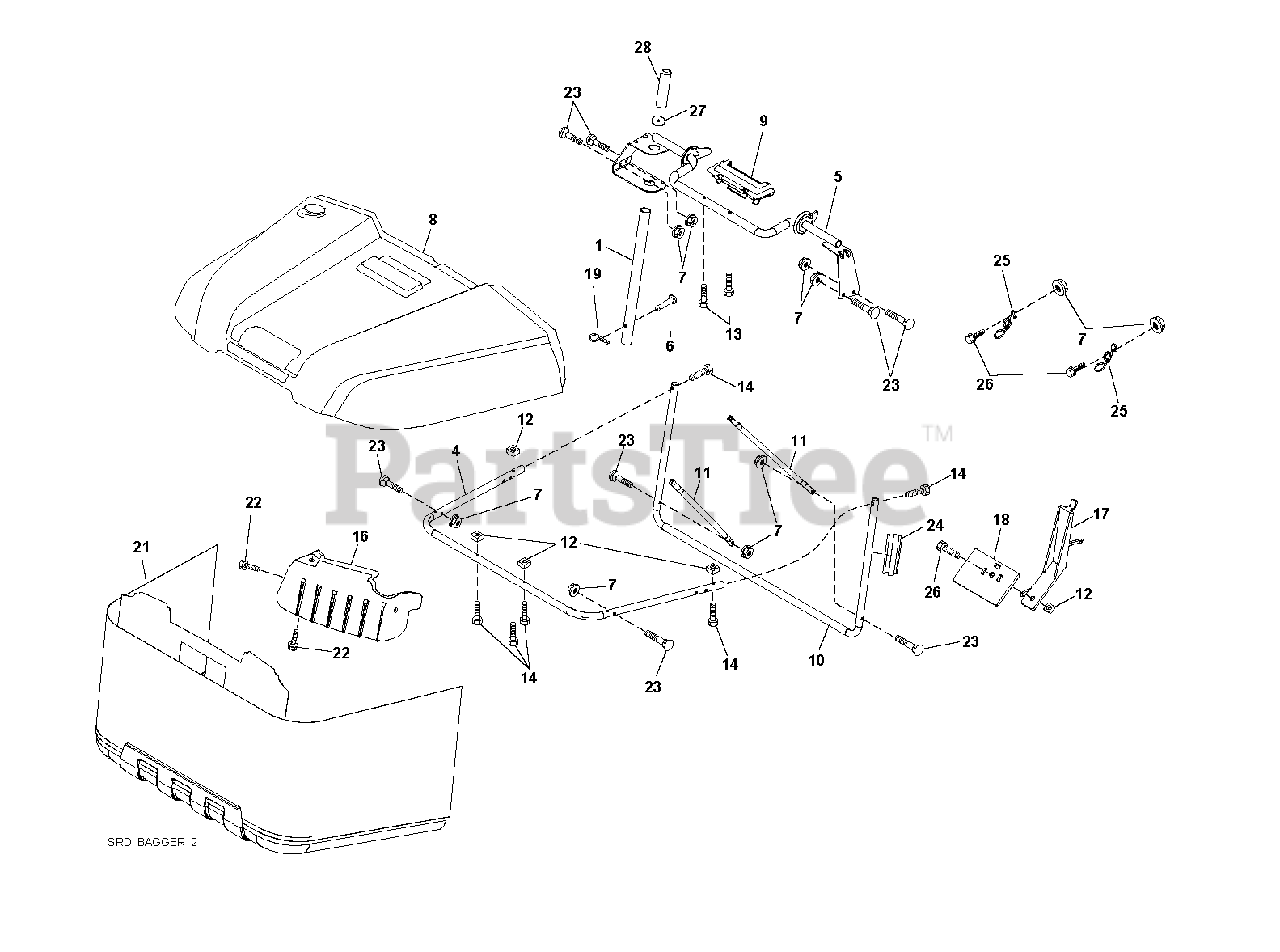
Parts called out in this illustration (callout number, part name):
1	TUBE HANDLE
6	RIVET,DRILLED
7	NUT T
19	RETAINER-SPRNG RB
22	SCREW.HI-LO.CONSOLE
26	SCREW HEX CRT
28	GRIP.HANDLE.BLACK
